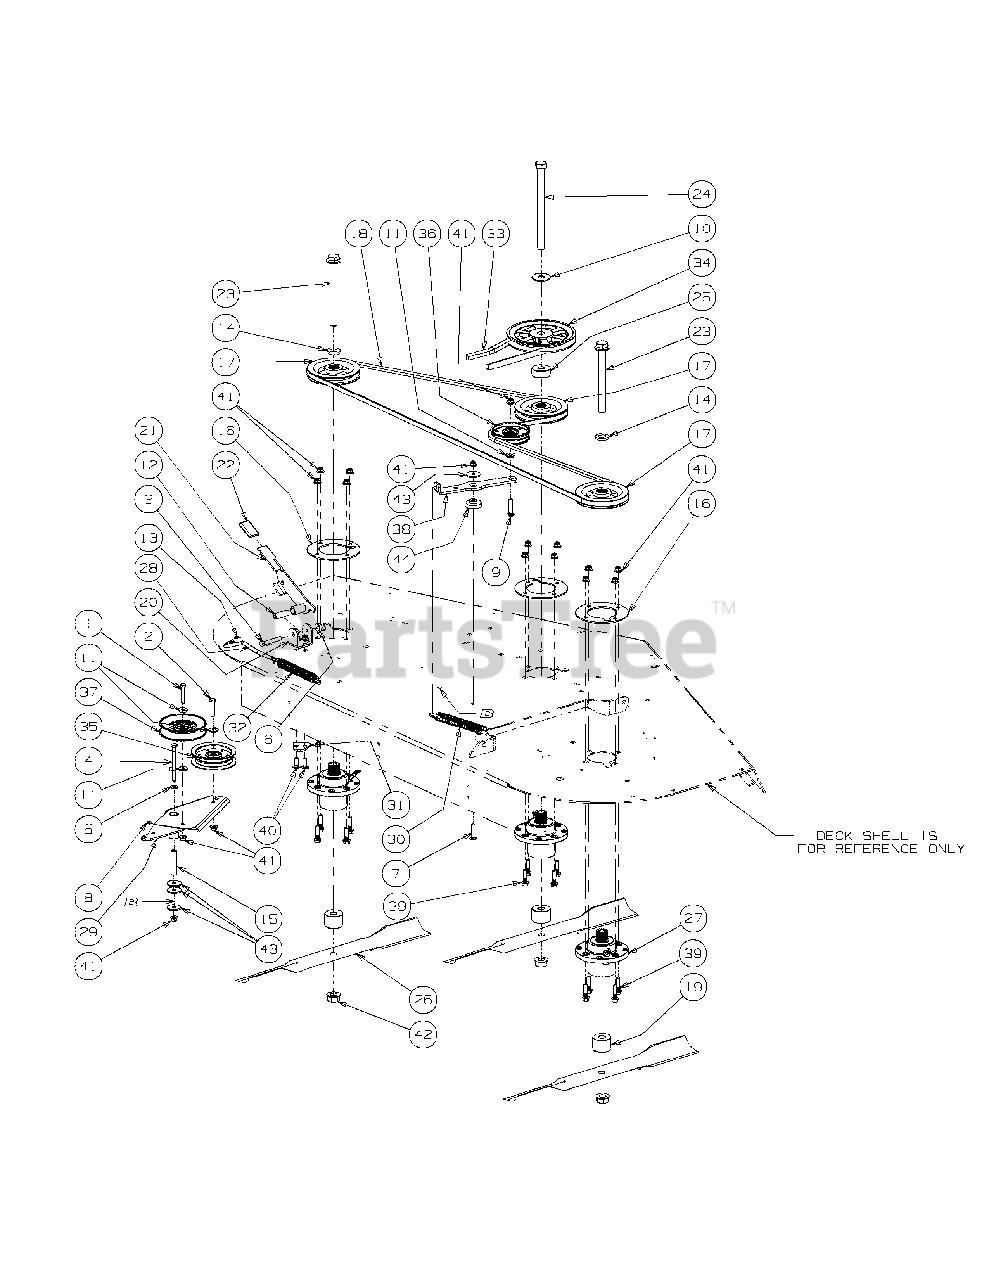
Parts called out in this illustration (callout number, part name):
1	Hex Cap Screw, 3/8-16 x 2.00
2	Hex Cap Screw, 3/8-16 x 1-3/4
3	Hex Cap Screw, #/8-16 x 2-1/2
4	Hex Cap Screw, 3/8-16 x 4.00
5	Washer, 3/8
6	Flange Lock Hex Nut, 3/8-16
7	Carriage Bolt, 3/81-6 x 1-1/2
8	Grease Fitting, 1/4-28 x 3/16
9	Hex Carriage Screw, 3/8-16, 1.75
10	Flat Washer, .781 ID 2.00 OD, .105
11	Flat Washer, .406 ID, 1.0 OD, .105
12	Spacer, .39 ID x .63 OD x 1.75
13	Cotter Pin, .072 x 1.12 Long
14	Spacer .812 ID x .268 LG
15	Spacer, .39 ID x .625 OD x 2.75
16	Aluminum Spindle Support Plate
17	V-Pulley, 5.75 OD
18	V-Belt, B Section x 124.0 Lg
19	Spacer, .760 ID x 2.00 OD x 1.28
20	Tension Idler U-Bracket
21	Handle Tension Weldment
22	Tension Idler Handle Grip
23	Hex Cap Screw, 3/4-16, 7.50
24	Hex Cap Screw, 3/4-16, 9.50
25	Spacer, .76 ID x 2.0 OD x .790
26	Bahia Blade, 25.0, .756 ID
27	Aluminum Spindle Assembly
28	Spring Tension Rod
29	Idler Arm Assembly includes:
29	Bearing Sleeve
30	Extension Spring, .94 x OD x 7.57
31	Adaptor Plate
32	Extension Spring, .94 OD x 7.72 Lg
33	V-Belt, B Section x 107.0
34	V-Pulley, 7.450 OD x .750 Bore, Cast
35	Idler Pulley, 4.06 OD
36	Idler Pulley, 4.06 Dia.
37	Idler Pulley, 5.06 Dia.
39	Bolt, 3/8-16 x 1.5
40	Carriage Bolt, 3/8-16 x 1
41	Nut, 3/8-16, Nylon Flange Lock
42	Flange Hex Nut, 3/4-16
43	Washer, .390 x 1.500 x .134
